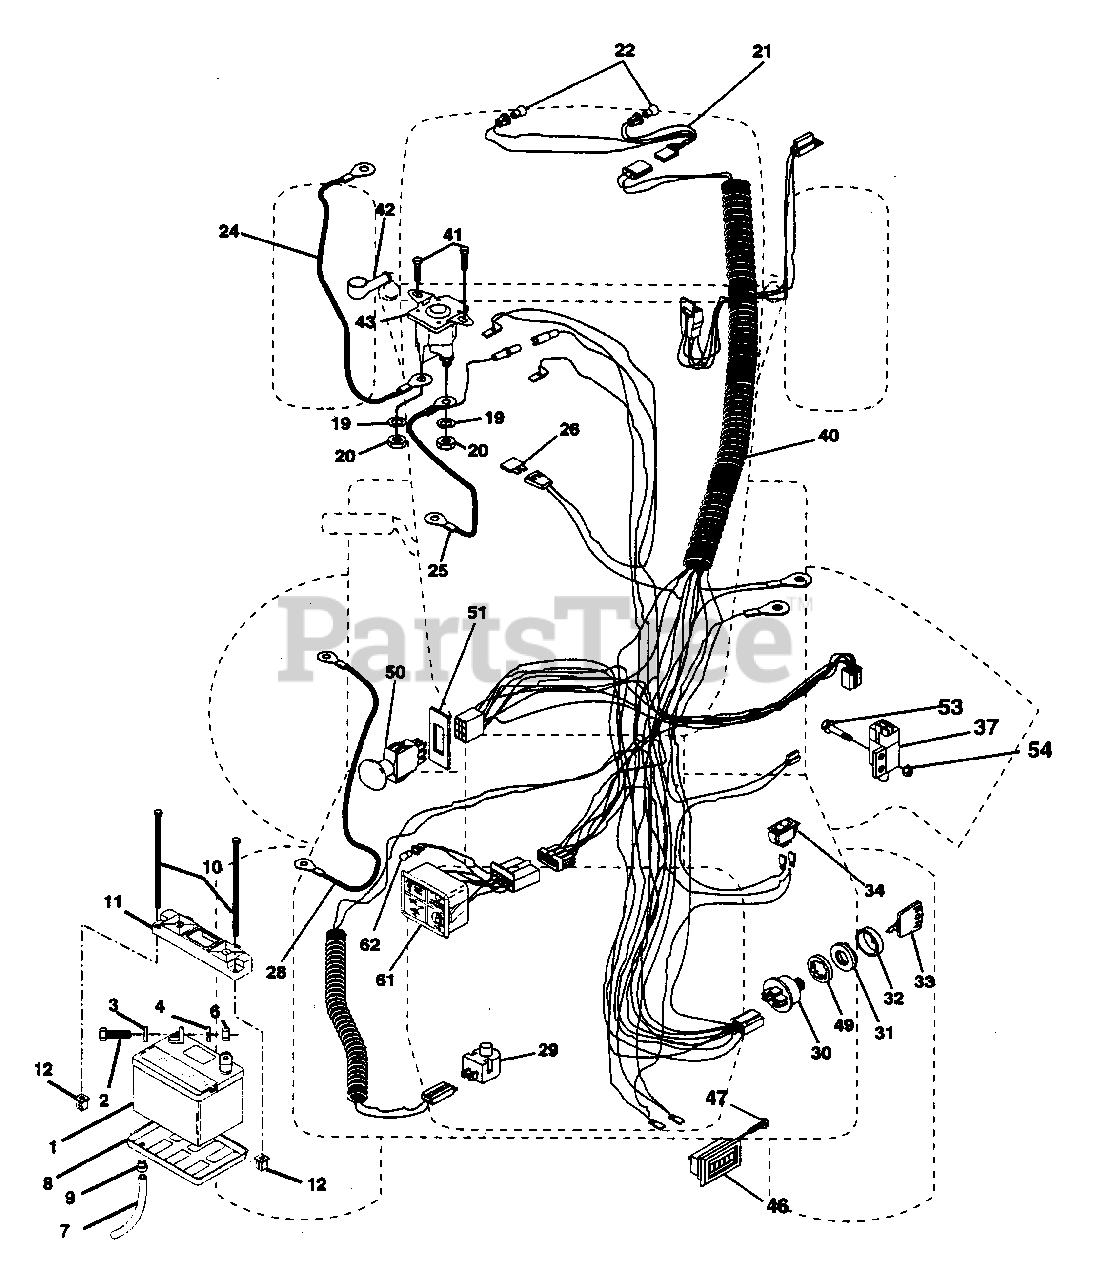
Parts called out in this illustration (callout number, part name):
1	Battery (AYP part number)
2	Bolt Hex Head 1/4-20 x 3/4 (AYP part number)
3	Washer, Lock 1/4 (AYP part number)
4	Washer 9/32 x 5/8 x 16 Ga (AYP part number)
6	Nut Fin Hex 1/4-20 (AYP part number)
7	Tube Plastic (AYP part number)
8	Tray, Battery (AYP part number)
9	Clamp, Hose (AYP part number)
10	Bolt, Battery Front 1/4-20 x 7.5 Zinc (AYP part number)
11	Holddown Battery Dash Mount (AYP part number)
12	Nut, Push Nylon 1.4" Battery Front (AYP part number)
19	Washer, Lock 1/4 (AYP part number)
20	Nut, Jam Hex 1/4-20 (AYP part number)
21	Harness Socket Light w/4152J (AYP part number)
22	Bulb Light (AYP part number)
24	Cable, Starter (AYP part number)
25	Cable, Battery (AYP part number)
26	Fuse (AYP part number)
28	Cable, Ground (AYP part number)
29	Switch, Plunger (AYP part number)
30	Switch, Ign (AYP part number)
31	Nut, Ignition Switch (AYP part number)
32	Cover Switch Key (AYP part number)
33	Key (AYP part number)
34	Switch, Light (AYP part number)
37	Intlk Switch (AYP part number)
40	Harness Ign. (AYP part number)
41	Screw 1/4-20 x 1/2 (AYP part number)
42	Cover, Terminal Red (AYP part number)
43	Solenoid (AYP part number)
46	Meter Hour (AYP part number)
47	Screw #10-24 x 1/2 (AYP part number)
49	Washer, Lock Internal Tooth 5/8 (AYP part number)
50	Switch, PTO (AYP part number)
51	Ring Retainer PTO (AYP part number)
53	Screw Hex Washer Hd #10-32 x 1 (AYP part number)
54	Nut Keps #10-32 (AYP part number)
61	Light Pkg Asm (AYP part number)
62	Bulb, Light Pkg. (AYP part number)
